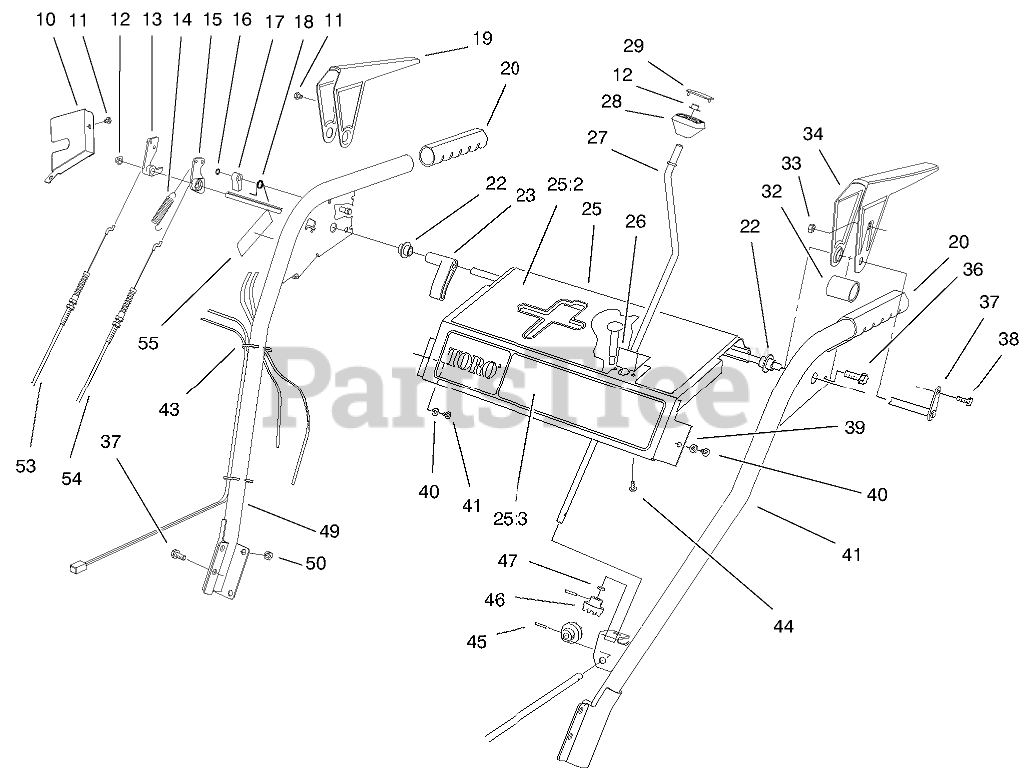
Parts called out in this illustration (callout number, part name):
10	COVER-LOCK, LEVER
11	SCREW-HH
12	RETAINER-PUSH ON
13	TANG-LOCKING
14	SPRING-EXTENSION
15	CAM-RELEASE
16	E-RING-RETAINER
17	LATCH-LOCKING
18	SPRING-TORSION
19	LEVER-TRACTION, RH
20	GRIP-HANDLE
22	BUSHING-LEVER
23	LEVER-TRIP
25	CONTROL PANEL/DECAL ASM (38543)
25:2	DECAL-CONTROL
25:3	DECAL-FRONT PANEL (824)
26	PLATE-GUIDE
27	CRANK-ROD, CHUTE
28	KNOB-CONTROL, CHUTE
29	COVER-KNOB
32	SPACER-LEVER, TRACTION
33	NUT-LOCK, NI
34	LEVER-TRACTION, LH
36	SCREW-HWHTF
37	CROSS ROD ASM
38	SCREW-HWH
39	WASHER-FLAT
40	SCREW-HWHTF
41	LH HANDLE ASM
43	TIE-CABLE
44	SCREW
45	PIN-SPRING
46	GEAR-UNIVERSAL
47	WASHER-RUBBER
49	HANDLE ASM
49:2	DECAL-ADJUSTMENT
50	NUT-LOCK, NI
53	CABLE-IMPELLER
54	CABLE-TRACTION
